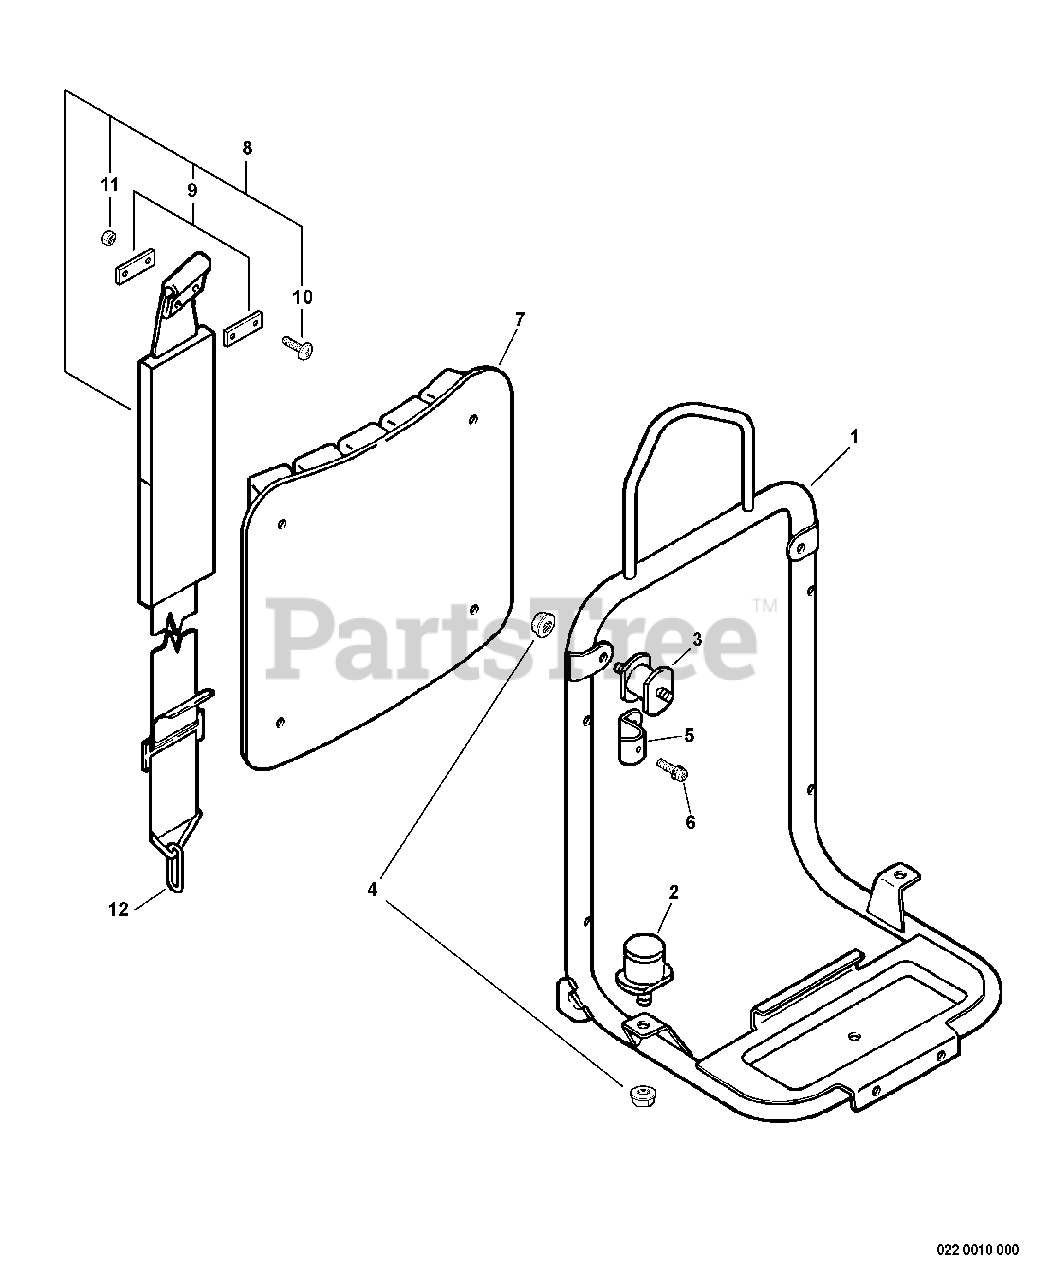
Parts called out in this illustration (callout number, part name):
1	FRAME, BACKPACK
4	NUT - 6 -- FLANGE
5	BRACKET, CUSHION
6	SCREW - 5X10
7	CUSHION, BACKPACK
8	BACKPACK STRAP ASSY
10	SCREW - 5X16
11	LOCKNUT - 5
12	RING, STRAP
